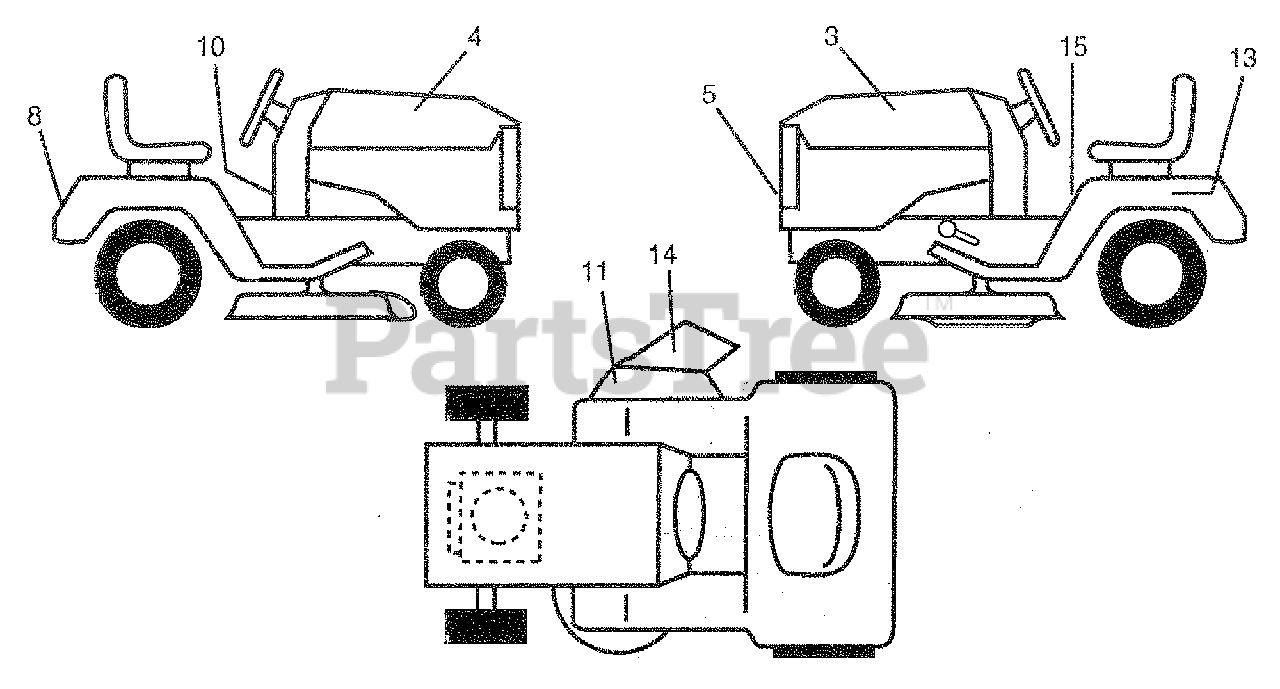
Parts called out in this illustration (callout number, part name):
3	Decal, Hood, L. H.
4	Decai, Hood, R. H.
5	Decal, Logo, Grill
8	Decai, Logo, Fender
10	Decal, Operating Instruction
11	Decal, Warning
13	Decal, Caution, Battery
14	Decaf, Caution, Deflector,
15	Decal, Caution
